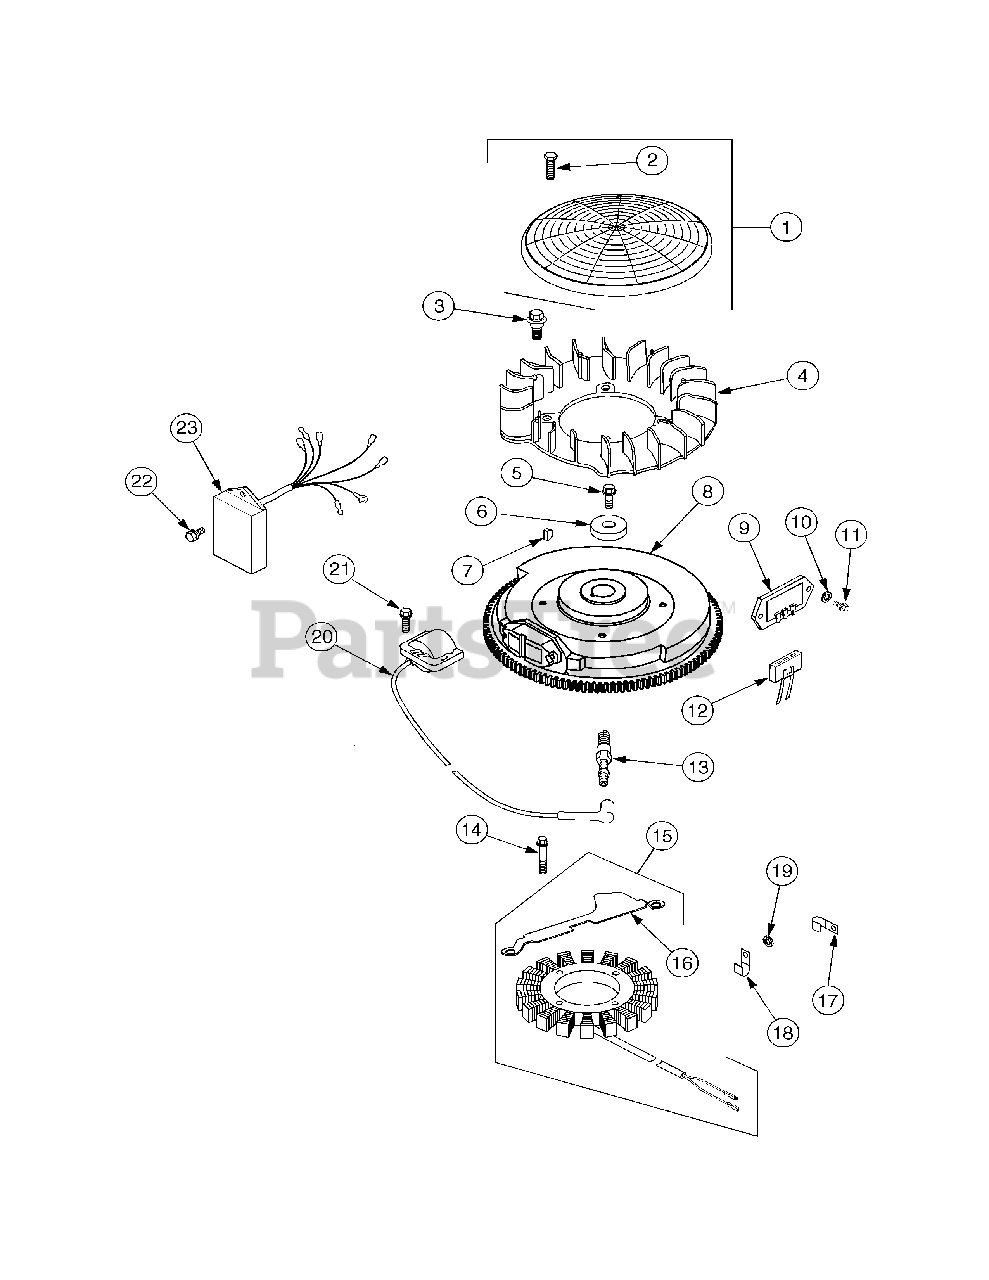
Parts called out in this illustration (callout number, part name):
1	Kit, Grass Screen
2	Screw, Hex Sems
3	Bolt, Shoulder
4	Fan
5	Screw, Hx Flange, M10-1.5 x 46
6	Washer, Plain, 3/8
8	Flywheel
9	Rectifier-Regulator
10	Washer, Plain, 3/16
11	Screw, Phillips Hd, 11-16 x 7/8
12	Connector
13	Spark Plug
14	Screw, Hx Cap, M5-0.8 x 25
15	Kit, 15 Amp Stator
16	Bracket, Stator Wire
17	Clip, Cable
19	Washer, Plain, 1/4
20	Module, Ignition
21	Screw, Hx Flange, M5-0.8 x 20
22	Module, Speed Advance
23	Screw, M4 x 0.7 x 10
